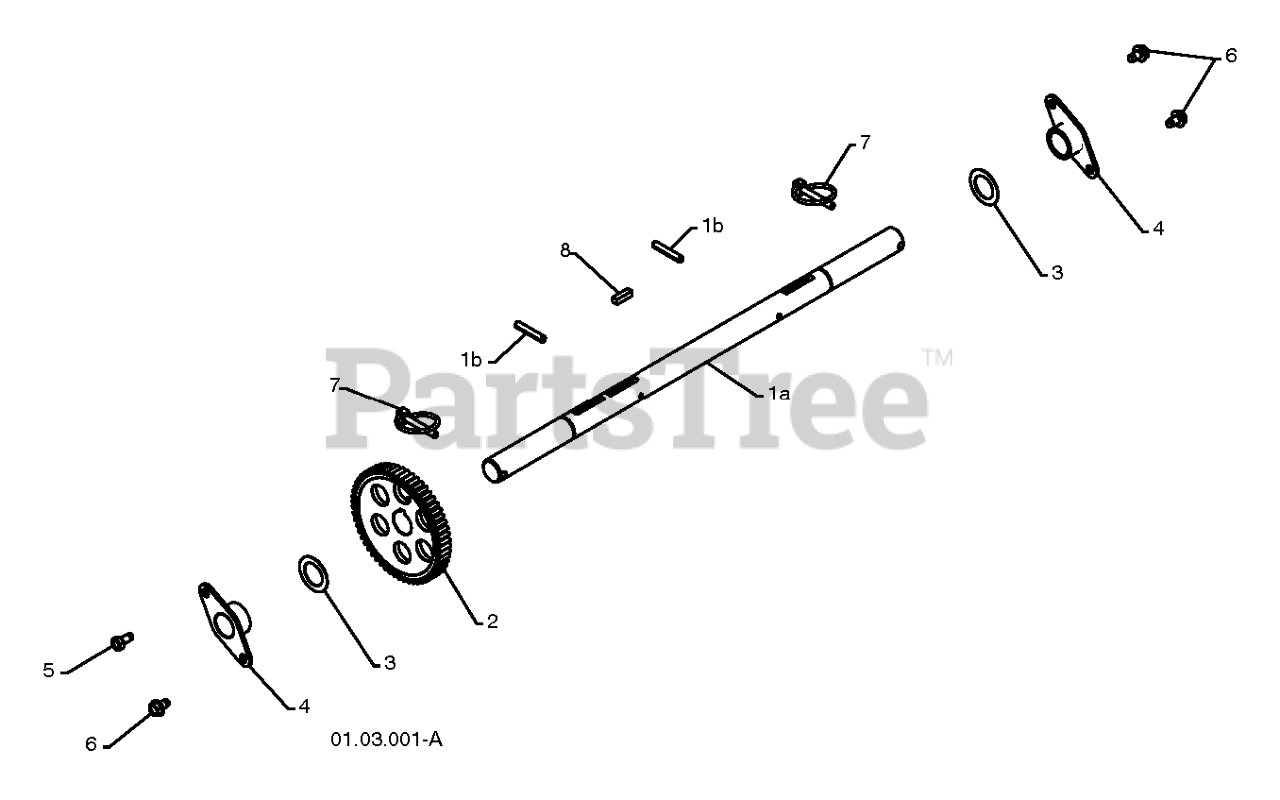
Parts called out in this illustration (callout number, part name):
1	AXLE.ASM.SHAFT.W/ROLLPIN.PS
1A	SHAFT.AXLE.POWER.STEERING
1B	PIN.ROLL.3/16
2	GEAR, AXLE (58T)
2	SHAFT.ASM.LIFT.YT
3	WASHER TRUST 1"
3	PIN.GROOVE.5/16
4	BEARING, AXLE
4	RETAINING RING LT
6	Screw 5/16-18 x 1/2 Hex, Self Tapping 5/16-18 x 1/2
6	BEARING.NYLON
7	PIN KLIK, 1/4
7	GRIP HANDLE
8	KEY, SQUARE 1/4 X .875
8	REPL BY 532 12 59-25
11	LINK
12	LINK
13	RETAINER-SPRNG RB
15	LINK.SUSPENSION.FRONT
16	NUT.HEX.JAM.1/2-13
18	NUT.LK.W/WSH.1/2.
19	ARM.REAR.SUSPENSION
20	PIN.COTTER.7/16.BOW TI.
26	RETAINER CLIP
27	ROD ADJ LIFT
28	NUT
29	KNOB INF 3/8-16
31	BEARING.PIVOT.LIFT
32	NUT CROWNLOCK 3/8-24
36	POINTER, HEIGHT INDICATOR(2 2)
38	SCREW 5/16-18X1
41	HEIGHT INDICATOR
49	NUT
50	NUT PUSH M
